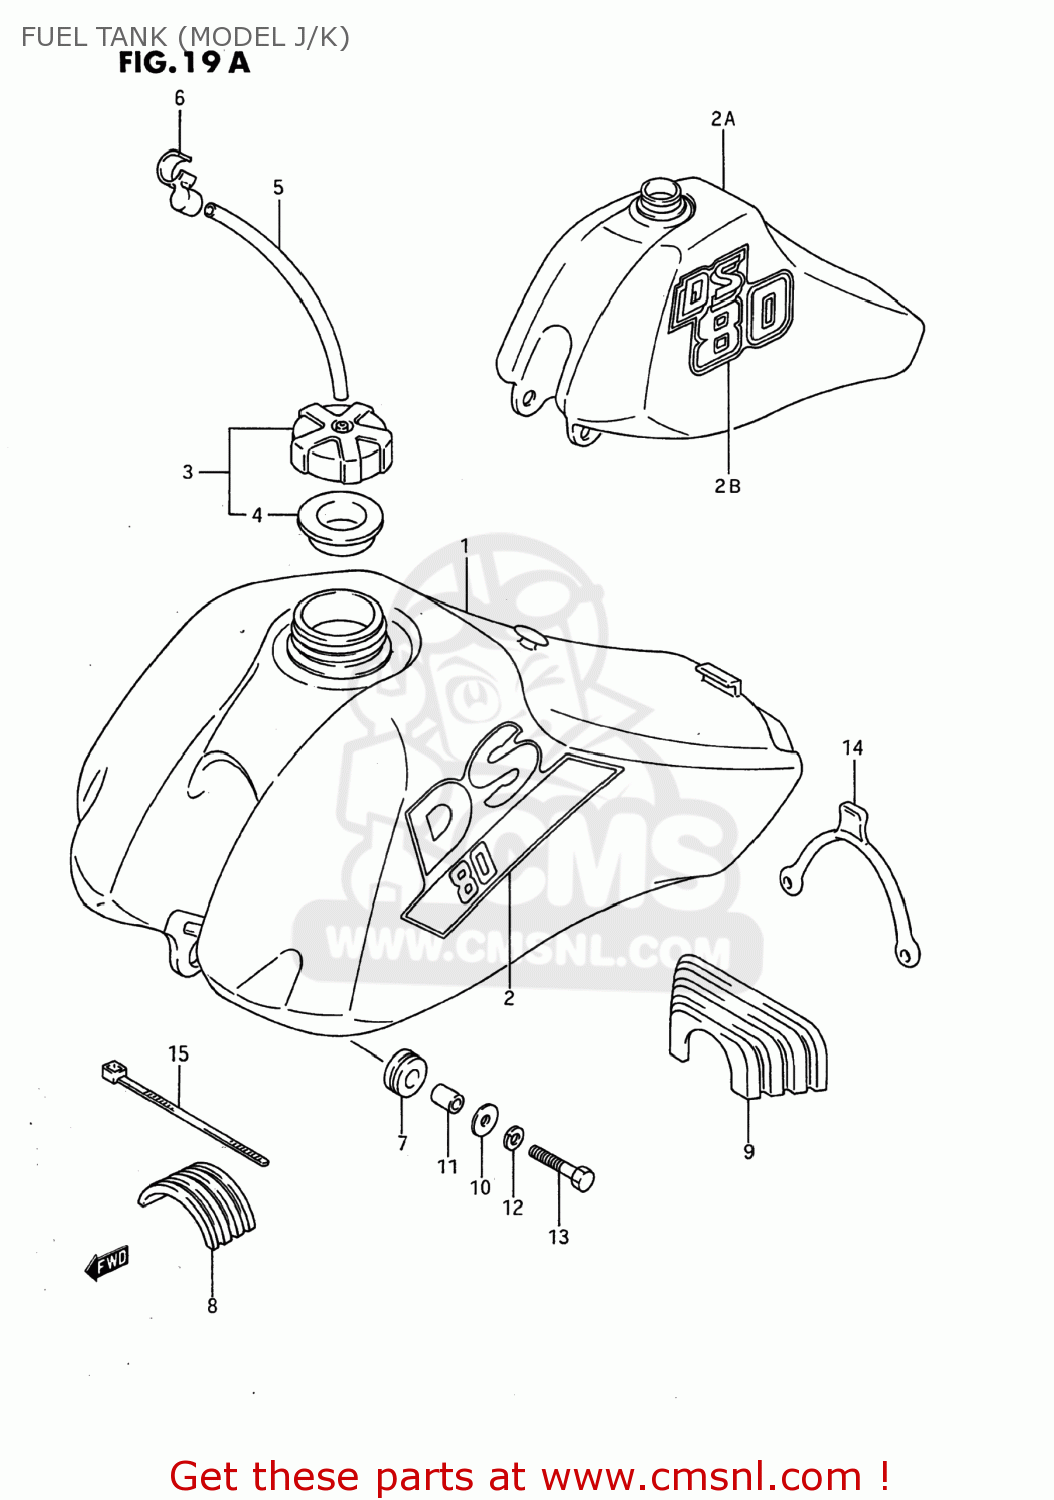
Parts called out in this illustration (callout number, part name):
1	TANK ASSEMBLY,FUEL
2	TAPE SET,FUEL TANK STRIPE
2A	TANK ASSEMBLY,FUEL
2B	TAPE,FUEL TANK
3	CAP SET,FUEL TANK
4	GASKET,FUEL TANK CAP (NAS)
5	HOSE(5X8.2X600)
6	CLAMP
7	CUSHION
8	CUSHION,FUEL TANK UPR FR
9	CUSHION,FUEL TANK UPR RR
10	WASHER (6.5X24X1.6)
11	SPACER (6.5X10.5X13.5)
12	WASHER,LOCK
13	BOLT
14	BAND,FUEL TANK RR
15	CLAMP
